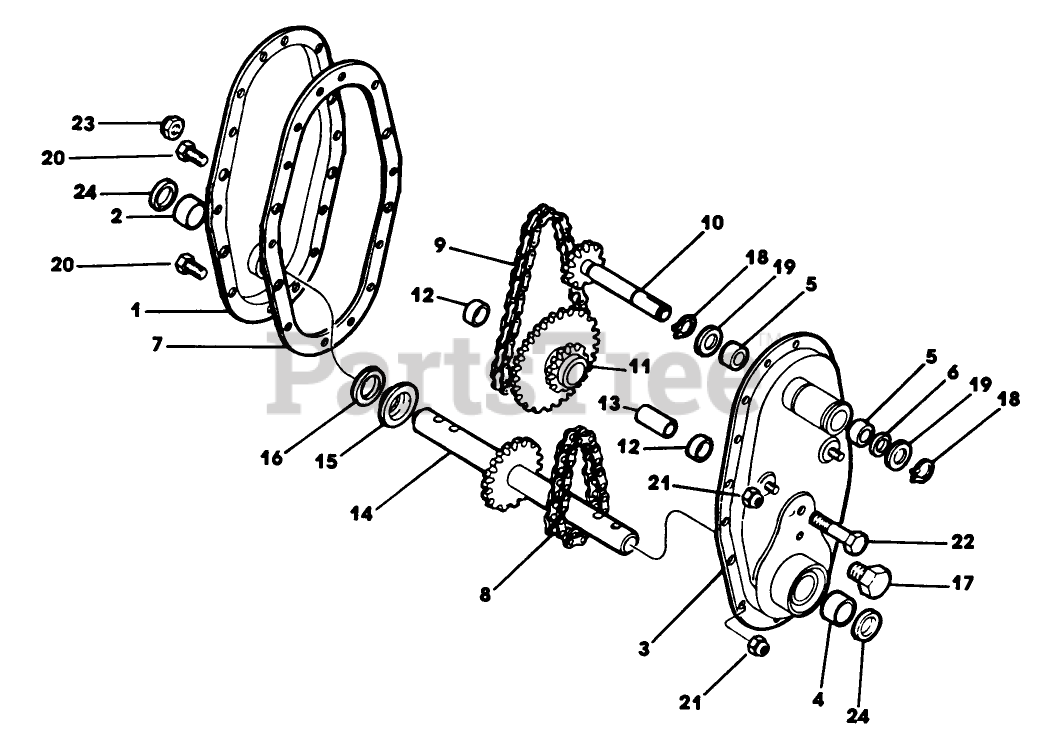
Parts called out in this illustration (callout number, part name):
6	SEAL-INPUT SHAFT
9	CHAIN - UPPER
10	INPUT SHAFT
13	SLEEVE - IDLER
15	SPACER CUP
16	SHIM-GEAR
18	RING-RETAINING
20	SCREW
21	NUT-LOCK, CONE
23	NUT-LOCKING
24	SEAL
